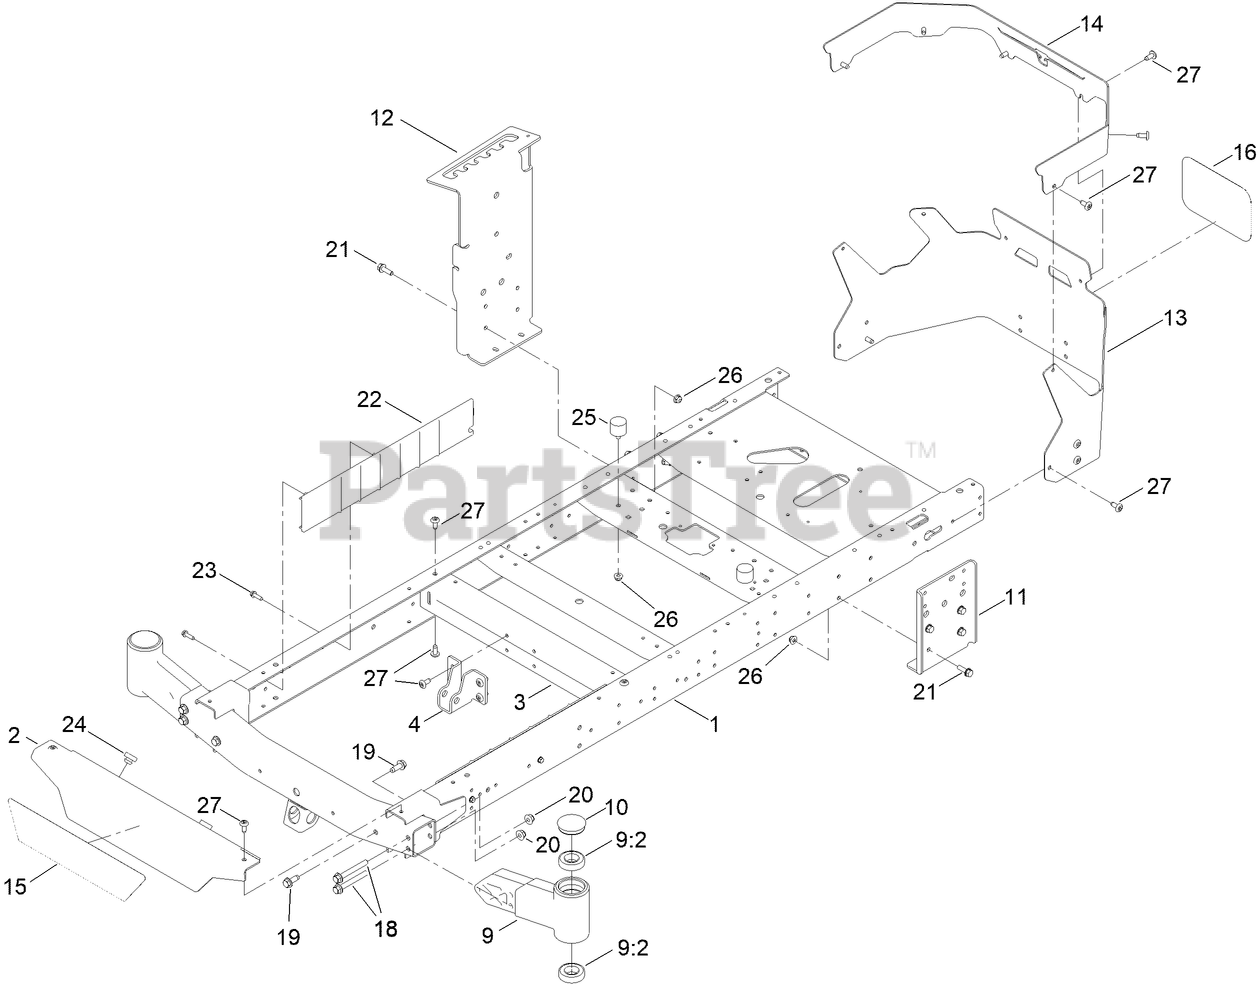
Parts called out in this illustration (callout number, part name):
1	FRAME ASM [RED]
2	FOOTREST
3	BRACE-CROSS, LOWER
4	BRACKET-MOUNT DAMPER, LOWER
9	AXLE STUB ASM
9:2	BEARING-BALL
10	CAP-GREASE
11	PLATE-MOUNT, DRIVE
12	PLATE-MOUNT, MR DRIVE
13	GUARD-REAR
14	GUARD-REAR, UPPER
15	DECAL-TIMECUTTER
16	DECAL-LOGO, SILVER
18	SCREW-HHF
19	SCREW-HWH
20	NUT-HF, NI
21	SCREW-HHF
22	GUARD-RAIL
23	SCREW-PLASTITE, HWH
24	BUMPER-RUBBER
25	BUMPER-RUBBER
26	NUT-HF
